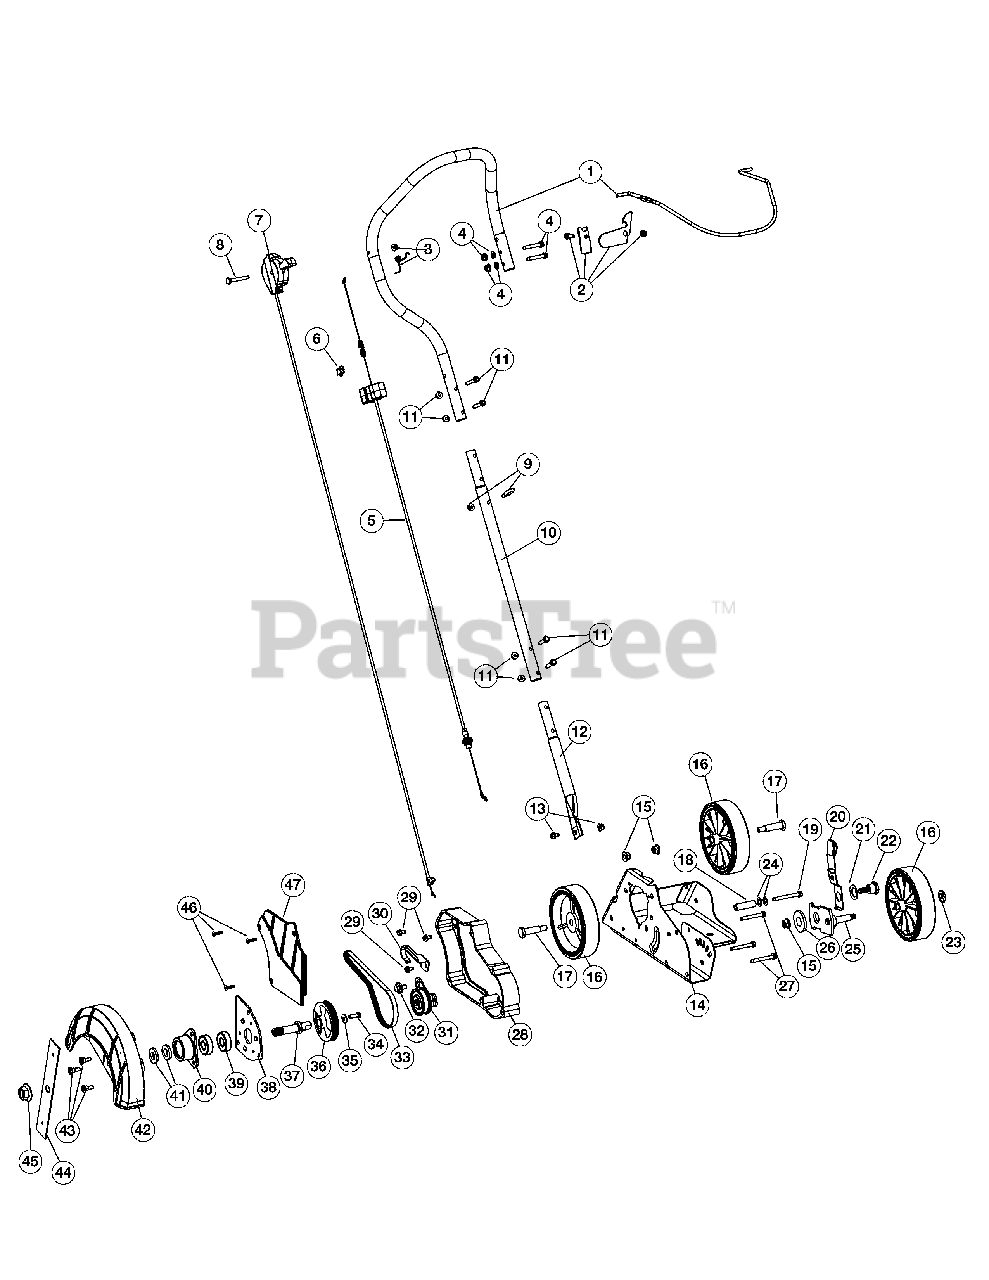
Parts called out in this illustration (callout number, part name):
1	Handle Assembly (Incl. Ref No. 2-4)
2	Lockout Lever Assembly
3	Bale Spring
4	Lockout Hardware Assembly
5	Tensioner Cable Assembly
7	Throttle Assembly
8	Throttle Hardware Assembly
9	Starter Rope Guide Assembly
10	Middle Handle Assembly (Incl. Ref No. 11)
11	Handle Hardware Assembly
12	Lower Handle
13	Lower Handle Screw & Nut Assembly
14	Edger Frame
15	Lock Nut
17	Wheel Bolt
18	Spacer
19	Spacer Screw
20	Height Adjustment Lever Assembly
21	Washer
22	Shoulder Screw
24	Washer
25	Pivot Arm
26	Height Adjustment Spacer
27	Spindle Plate Screw
28	Spindle Spacer
29	Screw
30	Belt Retainer
31	Idler Pulley Assembly
32	Shoulder Screw
34	Screw
35	Washer
36	Pulley
37	Blade Spindle
38	Spindle Plate
39	Bearing
40	Bearing Cup
41	Washer
42	Blade Guard
43	Screw
47	Belt Cover
